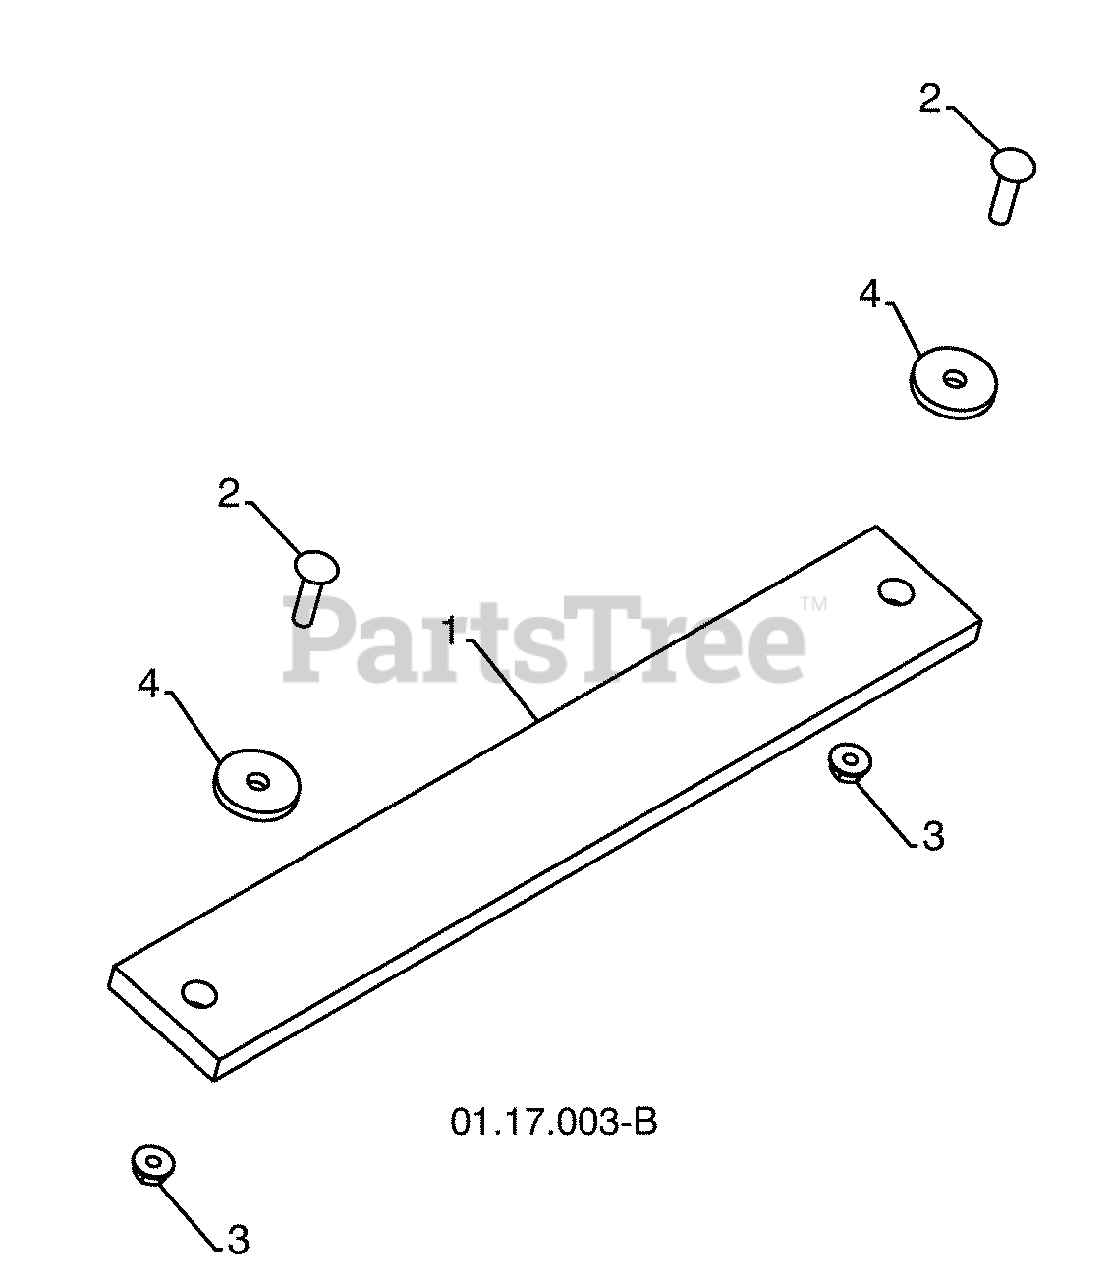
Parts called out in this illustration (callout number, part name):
1	WEIGHT BAR
2	CARRIAGE BOLT 5/16-18 X 1.25
3	NUT 5/16-18
